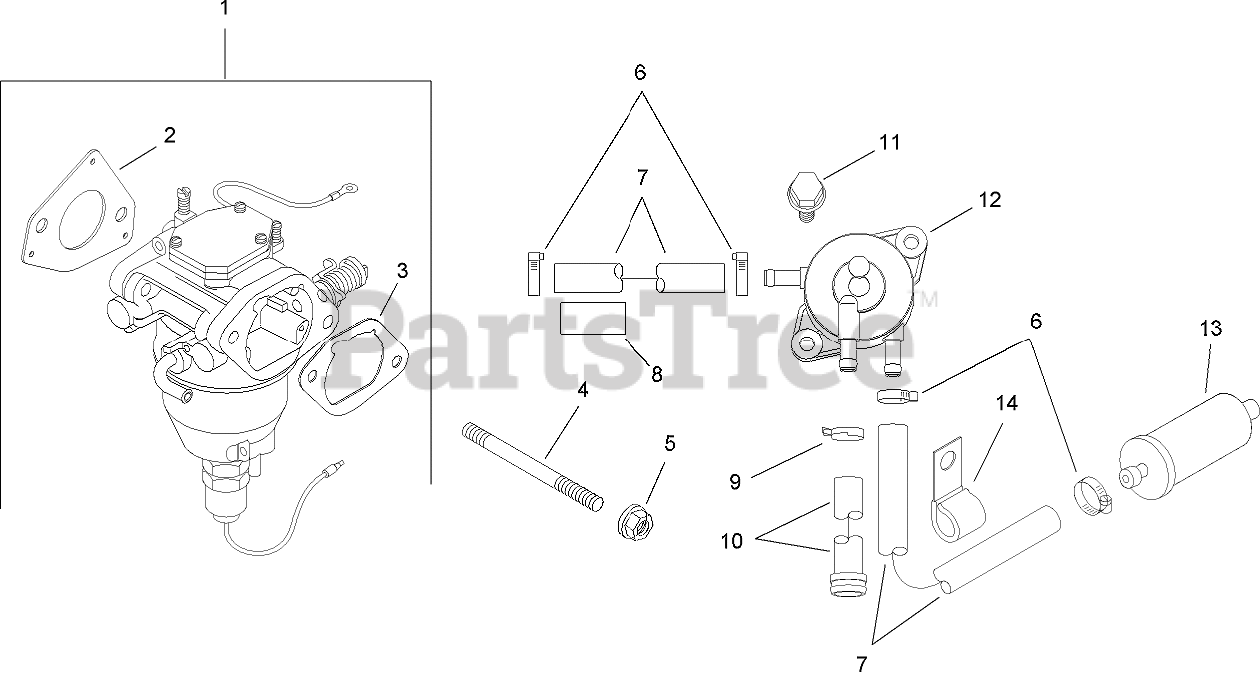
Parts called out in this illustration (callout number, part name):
1	Carburetor Kit w/Gaskets (Includes2-3)
2	GASKET-CARBURETOR
3	GASKET-BASE, AIR CLEANER
4	STUD (M6X1.0X106)
5	NUT-FLANGE (M6X1.0)
6	CLAMP-HOSE, SPRING (1/2)
7	LINE-FUEL (24.0 CUT TO LENGTH)
8	SLEEVE-ABRASION, ANTI
9	CLAMP-HOSE
10	FUEL PUMP HOSE KIT (W/CLAMP)
11	SCREW-TAP (M6X1.7X18)
12	PUMP-FUEL
13	Filter-Fuel
14	CLIP-CABLE
16	GASKET REPAIR/SERVICE KIT
18	SOLENOID VALVE REPAIR KIT
20	Overhaul w/gaskets Kit
22	Gasket Service Repair Kit
